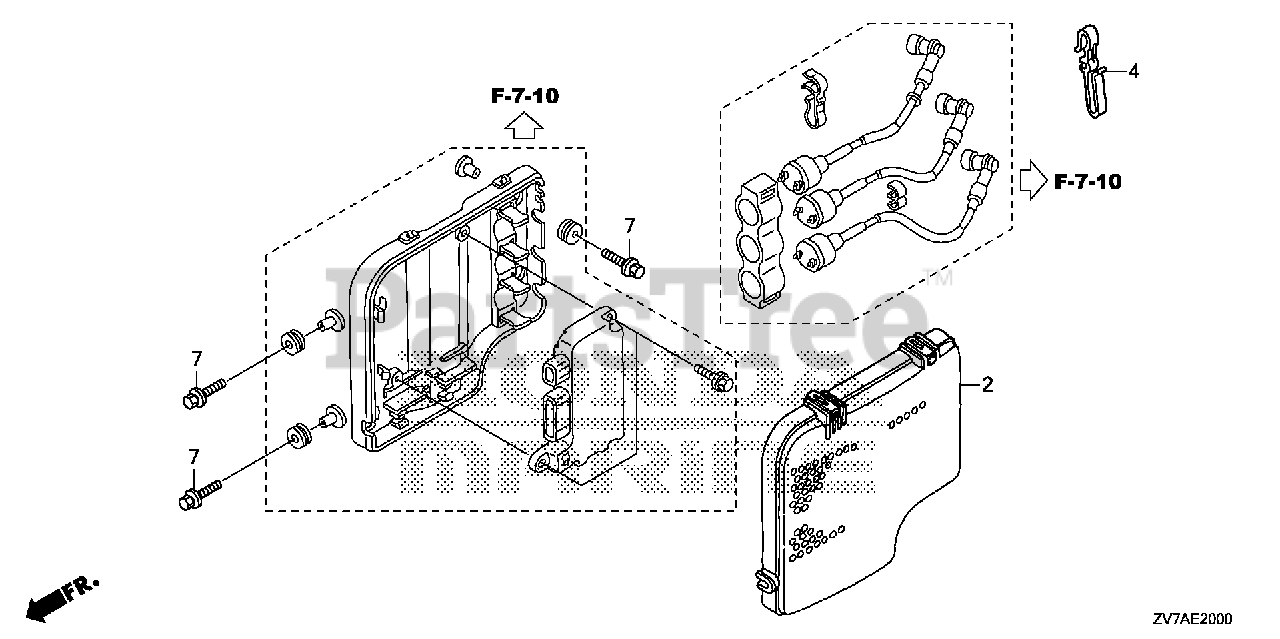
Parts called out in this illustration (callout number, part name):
2	COVER, IGNITION CONTROL MODULE (CDI)
4	CLAMP, CENTER WIRE
7	BOLT-WASHER (6X27) (CT200)
